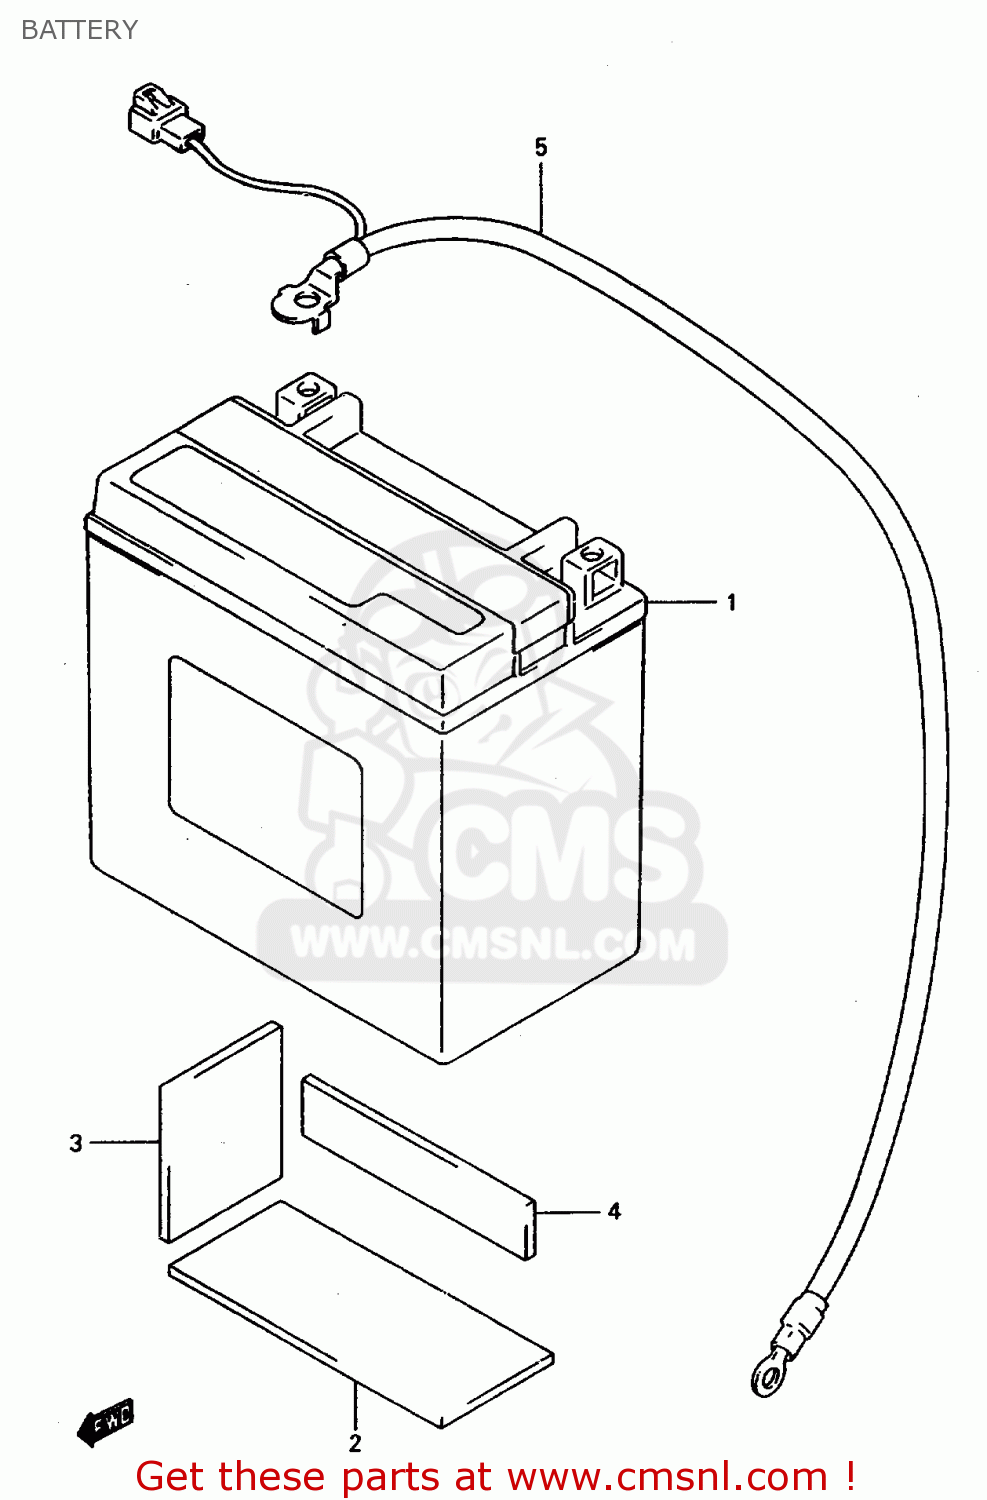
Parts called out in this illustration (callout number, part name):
1	BATTERY ASSY (12V) YTX14-BS
2	PROTECTOR(170X95X3.0)
3	PROTECTOR(170X95X3.0)
4	PROTECTOR(170X95X3.0)
5	WIRE,BATTERY MINUS LEAD
